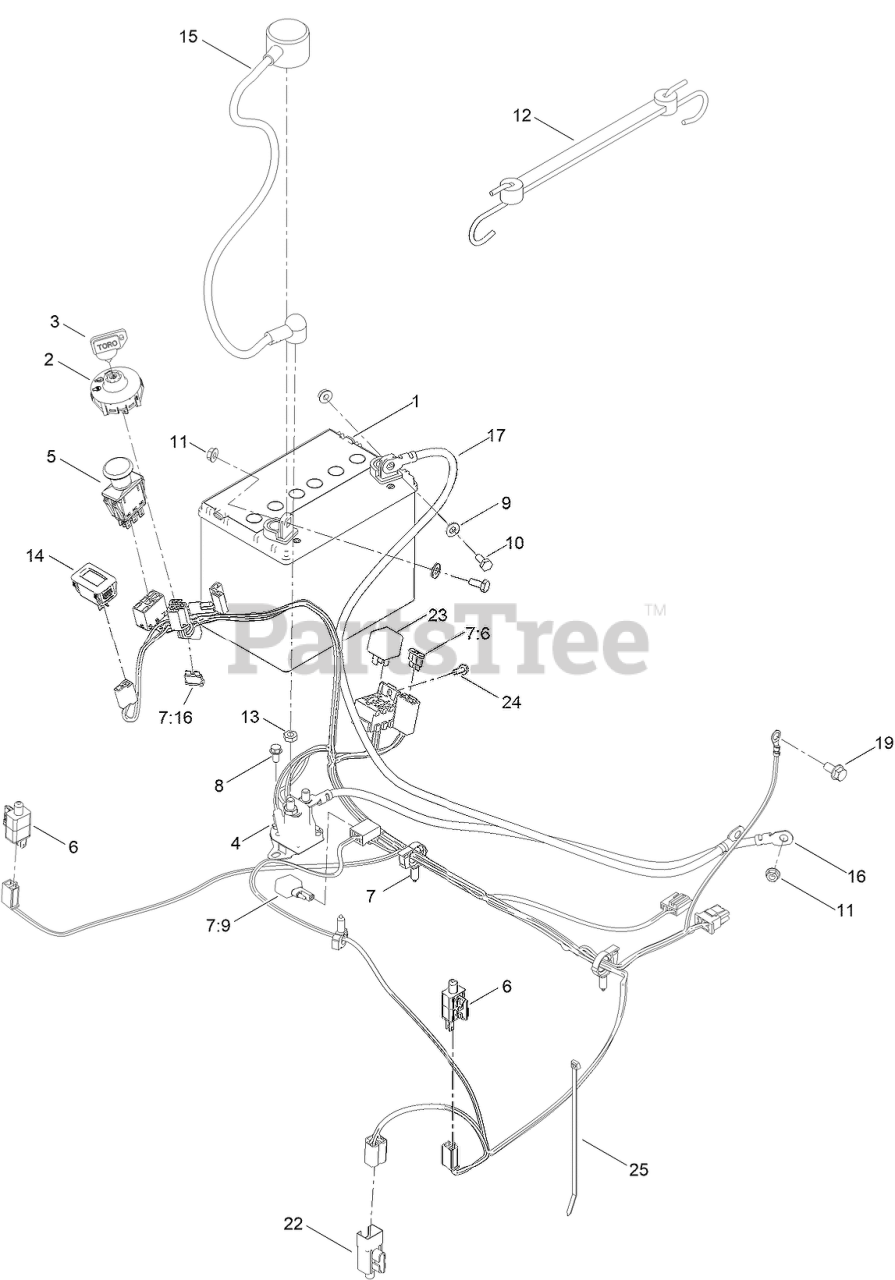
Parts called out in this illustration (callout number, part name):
1	BATTERY-DRY
2	SWITCH-IGNITION
3	KEY-IGNITION
4	SOLENOID
5	SWITCH-PTO
6	SWITCH
7	HARNESS-WIRE
7:6	FUSE-BLADE, 25 AMP
7:16	FUSE-BLADE, 15 AMP
8	SCREW-HWH
9	WASHER-FLAT
10	SCREW-HH
11	NUT-HF
12	HOLDDOWN-BATTERY
13	NUT-JAM
14	HOURMETER
15	CABLE-BATTERY, POSITIVE
16	CABLE-BATTERY, RD ASM
17	CABLE-BATTERY, NEGATIVE
19	SCREW-HHF
22	SWITCH-REVERSE
23	RELAY
24	SCREW-TAPTITE
25	TIE-CABLE
